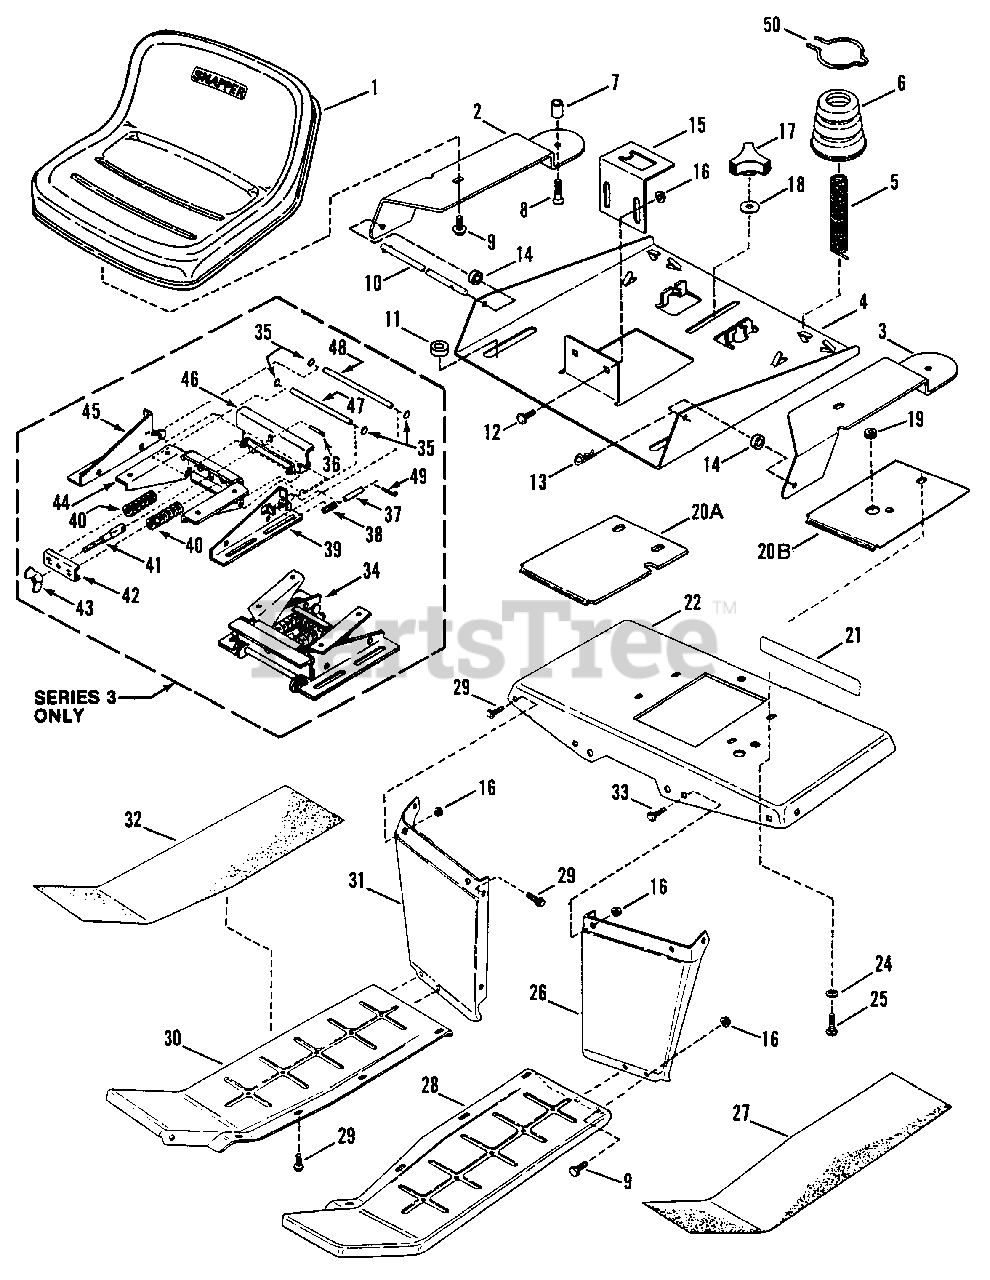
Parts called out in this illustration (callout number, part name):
1	SEAT, Operator's
2	BRACKET, Seat Support, R.H.
3	BRACKET, Seat Support, L.H.
4	SUPPORT, Seat
5	SPRING
6	CUSHION, Seat
8	SCREW, 5/16-18 x 1" Flat Head. Hex Recess
9	BOLT, 5/16-18 x 1/2" Hex Flange Lock, Grade 5
10	ROD, Seat Hinge
11	SPACER
12	BOLT, 5/16-18 x 5/8" Short Neck Carriage, Grade 5
13	PIN, 1/4" Hair
14	SPACER (NLA-83)
15	BRACKET, Switch
16	NUT, 5/16-18 Hex Flange Lock, Grade 5
17	KNOB, Seat Adjustment
18	WASHER, 5/16 Flat
19	GROMMET, Split
20A	COVER, Access
20B	COVER, Access
21	DECAL, Snapper
22	FENDER, Rear 33", 41" & 48" Decks (NLA)
24	RETAINER, Bolt
25	BOLT, 5/16-18 x 1" Square Neck Carriage
26	EXTENSION, Fender, Left Side
27	TREAD, Left Side (Non-Skid)
28	PANEL, Step, Left Side
29	SCREW, 5/16-18 x 5/8" Self-Tap
30	PANEL, Step, Right Side
31	EXTENSION, Fender, Right Side
32	TREAD, Right Side (Non-Skid)
33	BOLT, 5/16-18 x 1/2" Short Neck Carriage, Grade 5
34	ASSEMBLY, Seat Suspension
35	PUSH-NUT, 3/8"
36	PIN, 3/16 x 1-3/4" Grooved
37	PLUNGER
38	SPRING, Compression
39	MOUNTING ANGLE, R.H.
40	SPRING, Seat
41	ROD, Adjusting
42	RETAINER, Seat Spring
43	WING-NUT, 1/2-13
44	WELDMENT, Seat Hinge
45	MOUNTING ANGLE, L.H.
46	HINGE, Seat Weldment
47	PIN, Seat Hinge, 7.39 Length
48	PIN, Seat Hinge, 8.75 Length
49	COTTER-PIN, 3/12 x 3/4"
50	CLIP, Seat Cushion
